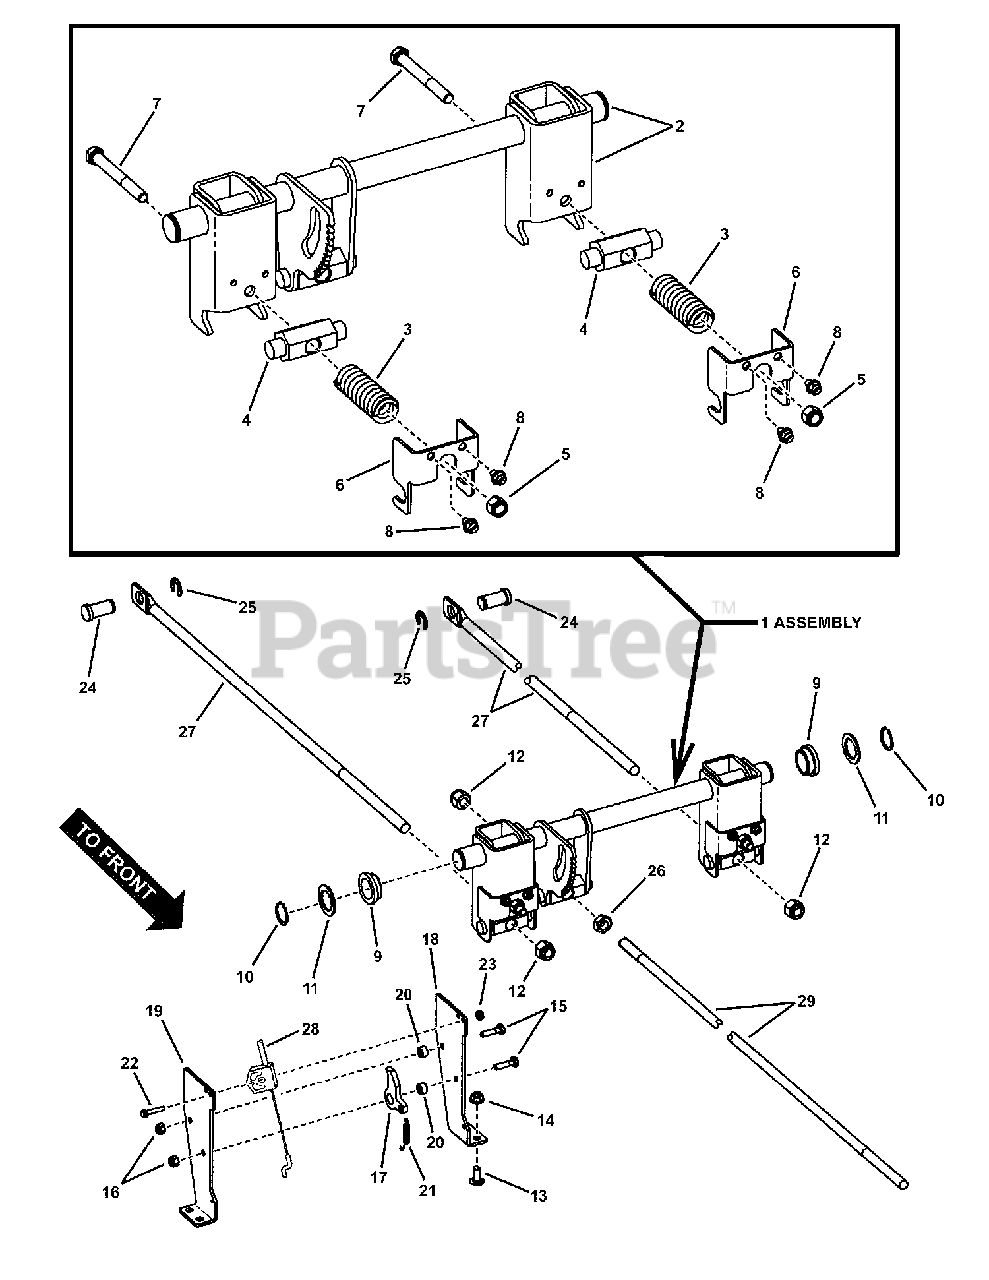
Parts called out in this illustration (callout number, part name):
1	BRAKE ASSEMBLY, Utility Vehicle (incl. items 2 thru 8)
2	WELDMENT, Rear CVT Brake Shaft
3	SPRING, CVT Brake
4	BRAKE SWIVEL, w/.531 Thru Hole
5	NUT, 3/8-16 Hex Nyloc
6	BRACKET, Swivel Retainer (Red)
7	SCREW, 3/8-16 x 3-1/4" Hex Head Cap, GR 5
8	SCREW, 1/4-20 x 3/8" Hex Washer Self-Tap
9	BEARING, 1" I.D.
10	RING, 1.00 Dia. External Retaining
11	BUSHING, 14 Gage Machine
12	NUT, 1/2-20 Hex Nyloc
13	BOLT, 5/16-18 x 3/4" Short Square Neck Carriage, GR 5
14	NUT, 5/16-18 Hex Flange Lock, GR 5
15	SCREW, 1/4-20 x 1" Hex Head Cap, GR 5
16	NUT, 1/4-20 Hex Nyloc
17	PAWL, Park Brake
18	BRACKET, LH Park Brake Pawl Pivot (Black)
19	BRACKET, RH Park Brake Pawl Pivot (Black)
20	SPACER, Park Brake
21	SPRING, Return, Extension
22	SCREW, #10-32 x 1" Hex Washer Self-Tap
23	NUT, #10-32 Hex Center Lock
24	PIN, Brake Anchor
25	RETAINING RING, 5/8" Shaft
26	NUT, 1/2-20 Hex Jam, GR 5 or B
27	BRAKE ROD, Rear CVT (1/2-20 thread)
28	CABLE, Parking Brake
29	ROD, Lower CVT Brake (1/2-20 thread, both ends)
